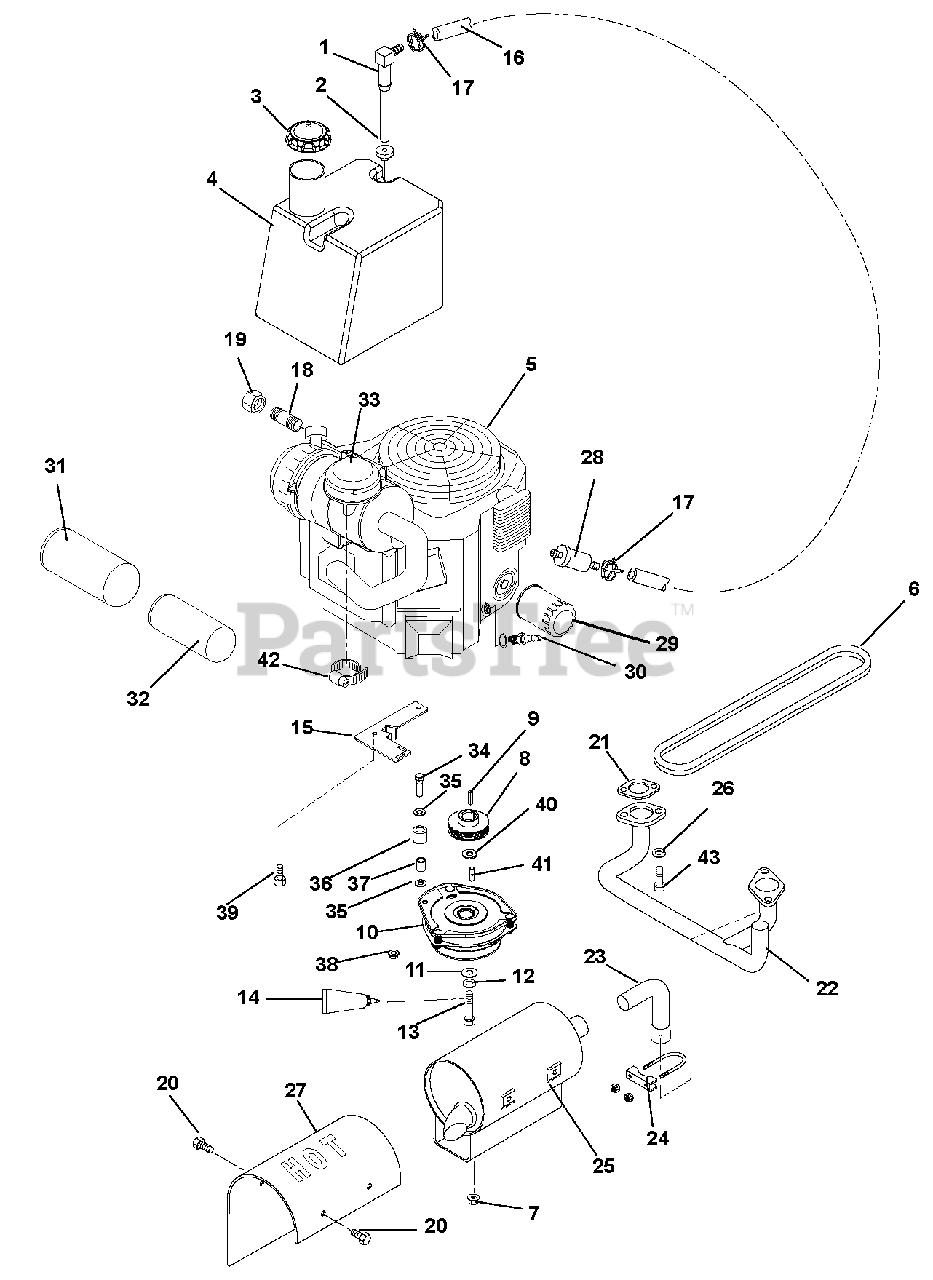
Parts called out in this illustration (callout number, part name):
1	AR
7	2
11	1
12	1
13	1
26	4
28	AR
29	AR
34	1
35	2
38	1
39	4
